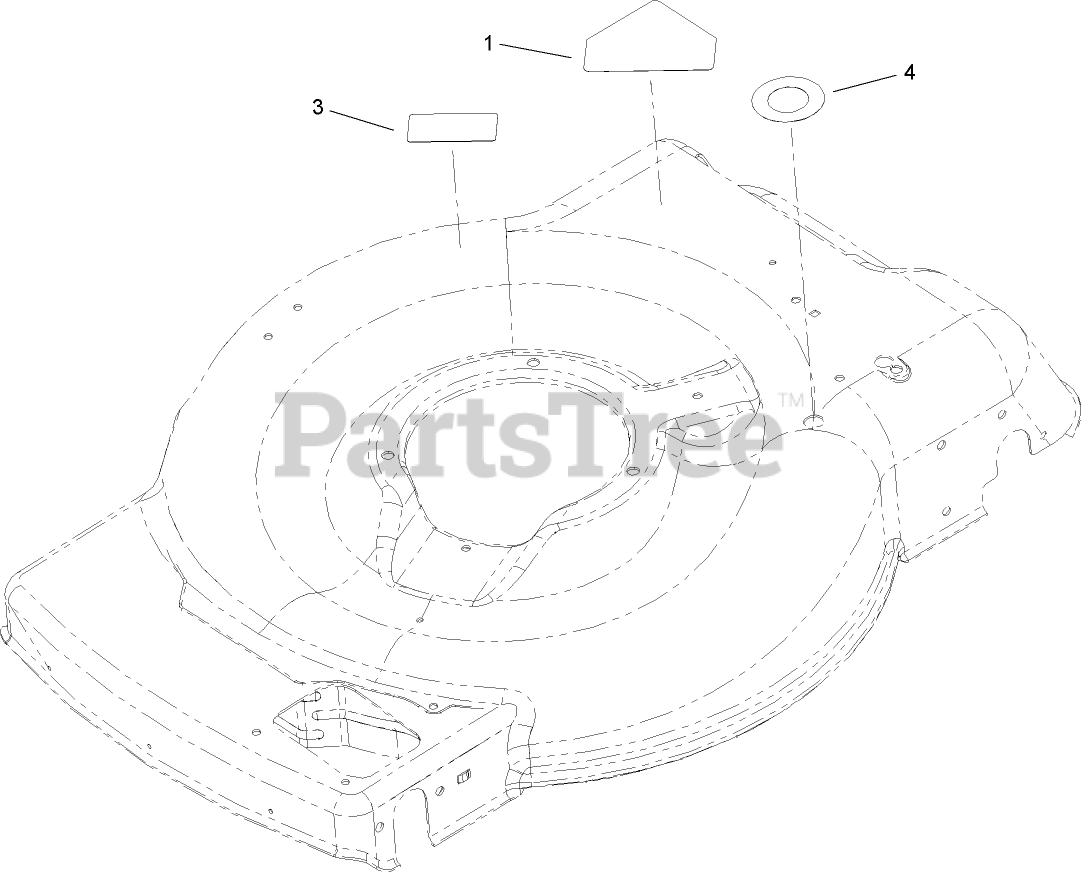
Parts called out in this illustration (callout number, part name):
1	DECAL-DANGER
3	DECAL-PLACEMENT, FOOT
4	DECAL-PORT, WASHOUT
